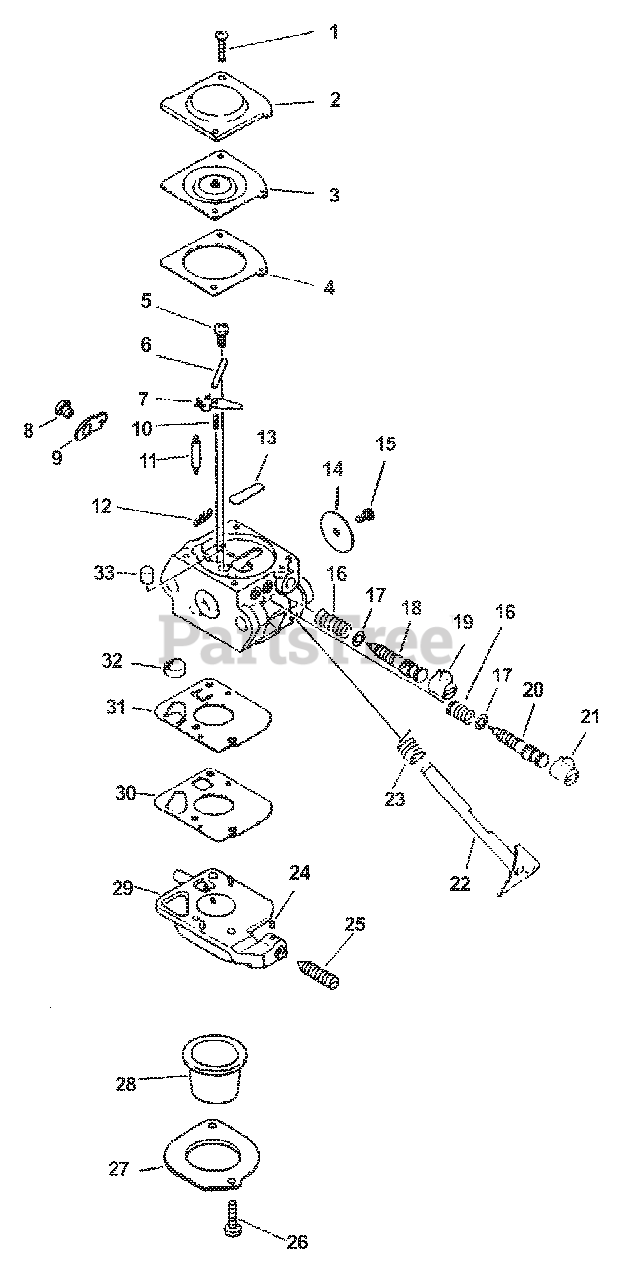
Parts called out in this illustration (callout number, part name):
2	COVER, DIAPHRAGM
3	DIAPHRAGM
4	GASKET, DIAPHRAGM
6	PIN, METERING LEVER
7	LEVER, METERING
9	LEVER, THROTTLE
10	SPRING, METERING LEVER
11	VALVE, INLET NEEDLE
13	PLUG, WELCH
14	VALVE, THROTTLE
15	SCREW 3×4.5
18	NEEDLE, LOW SPEED
19	CAP, LIMITER - WHITE
20	NEEDLE, HIGH SPEED
21	CAP, LIMITER
22	SHAFT, THROTTLE
23	SPRING, THROTTLE RETURN
24	PIECE, FRICTION
27	RETAINER
28	BULB, PURGE
29	BODY ASSY, PURGE
30	GASKET, PUMP
31	DIAPHRAGM, PUMP
32	STRAINER
33	NOZZLE, CHECK VALVE
